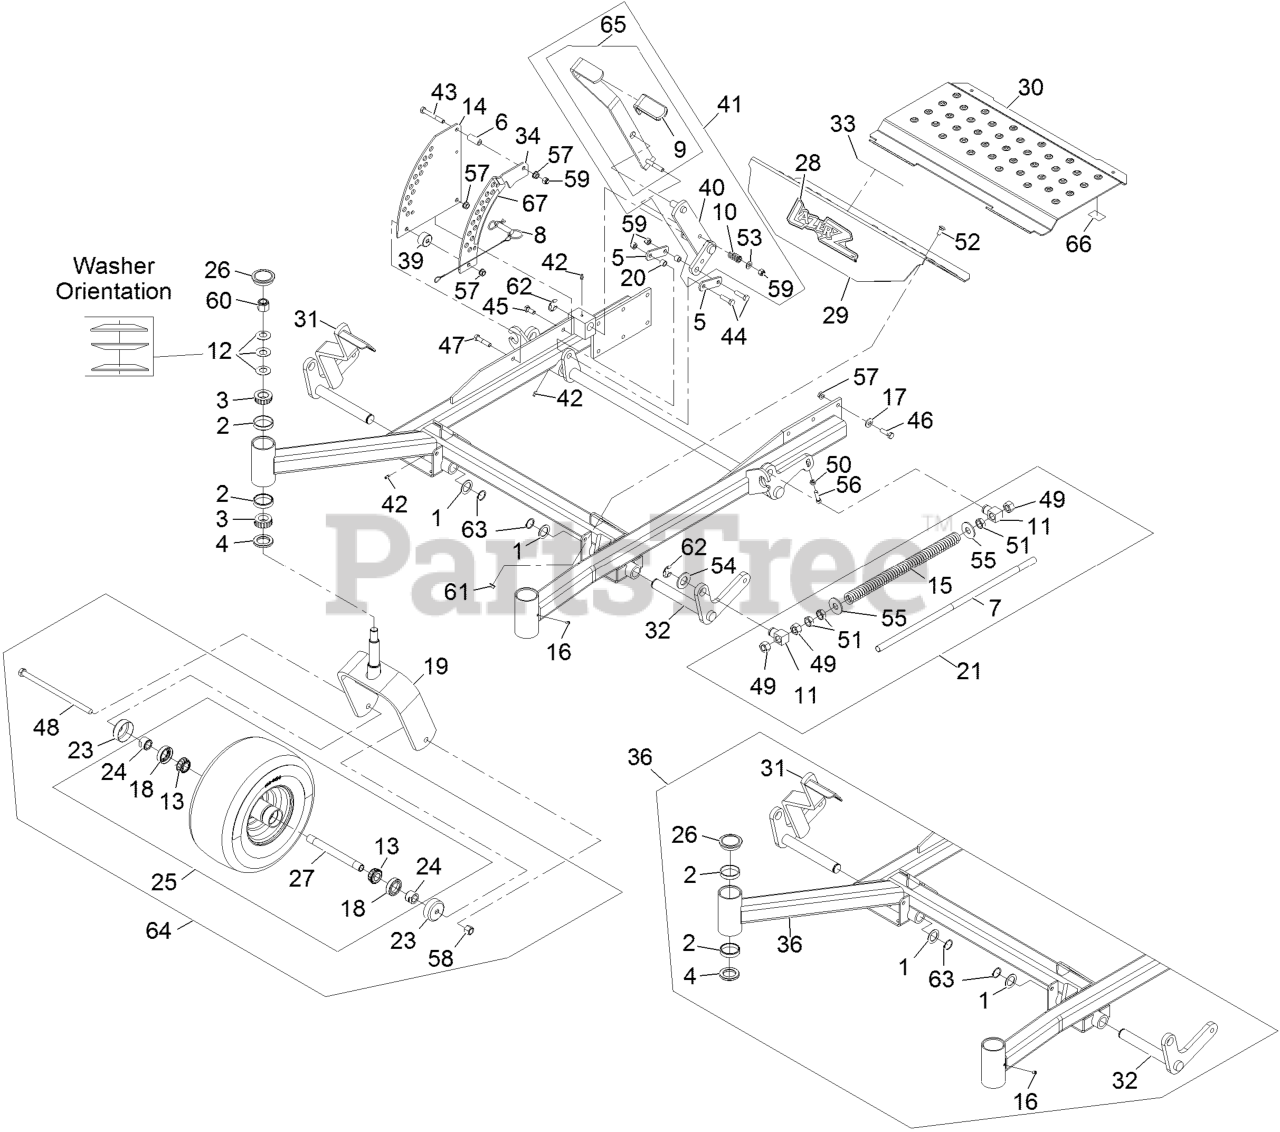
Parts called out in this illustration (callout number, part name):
1	WASHER-SPACER
2	CUP-BEARING
3	Cone-Bearing Tapered Roller
4	SEAL-GREASE
5	ARM-LIFT, DECK
6	BUSHING-LEVER, LIFT
7	ROD-LIFT, DECK
8	PIN-HITCH (W/LANYARD)
9	GRIP-LEVER, LIFT
10	SPRING-COMPRESSION
11	SWIVEL-DECK MOUNT, REAR
12	WASHER-BELLVILLE
13	BEARING-CONE, TAPERED ROLLER
14	PLATE-LIFT, DECK
15	SPRING,DECK SUPPORT
17	WASHER-BELLEVILLE
18	SEAL-CASTER
20	BUSHING
21	ASM,FRONT FRAME SPRING
23	GUARD-SEAL
24	SPACER-NUT
26	CAP-GREASE
28	DECAL,LAZER MODEL
29	ASM, FLOORPAN FRONT W/DEC
30	ASM, FLOORPAN LIFTOUT W/D
31	WLD,FRONT LIFT W/LEVER
32	WLD,FRONT LIFT SHAFT-LH
33	DECAL-SLOPE
34	PLATE-LIFT,DECK W/DECAL L
36	ASM, FRONT FRAME 72"
40	WLD,ARM DECK LIFT
41	ASM,Deck Lift Handle
42	FITTING-GREASE
43	SCREW-HH
44	SCREW-HH
45	SCREW-HH
46	SCREW-HH
47	SCREW-HH
48	SCREW-HH
49	NUT-HEX
50	NUT-JAM
51	NUT-JAM
52	BOLT-CARR
53	WASHER-FLAT
54	WASHER-FLAT
55	WASHER-FLAT
56	SCREW-HSH
57	NUT-HHF, WHIZ
58	NUT-LOCK, NI
59	NUT-LOCK, NI
60	NUT-LOCK, NI
62	RING-RETAINING, EXT
63	RING-RETAINING
64	WHEEL & TIRE ASM
65	LIFT LEVER/GRIP ASM
66	DECAL-GUARD
67	DECAL-HEIGHT, DECK
